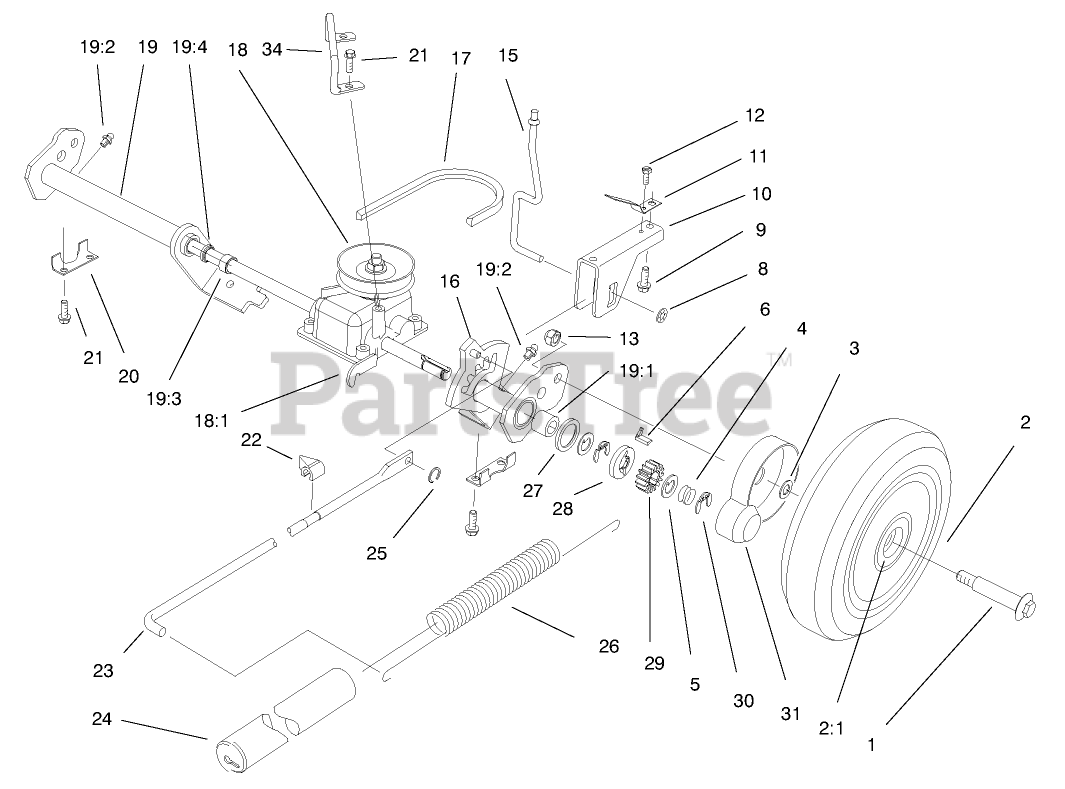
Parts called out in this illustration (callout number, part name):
1	BOLT-WHEEL
2:1	BUSHING
3	SPACER-COVER, WHEEL
4	SPRING-COMPRESSION
5	WASHER-THRUST, KEYED
6	KEY-ROCKING, LH
8	PUSHNUT
9	SCREW
10	SADDLE - HOC
12	SCREW 8 - 32 X 250
13	NUT-HEX
15	TRIGGER ROD
17	V-BELT
19	ASM - RH PIVOT ARM
19:2	FITTING-GREASE
19:3	BUSHING
19:4	SEAL-OIL
21	SCREW-HWH
22	INDICATOR-HEIGHT OF CUT
23	LINK ROD
24	COVER-SPRING
25	GRIP RING
26	SPRING-COUNTERBALANCE
27	RING-FRICTION
28	WASHER-CLUTCH
29	GEAR-PINION
30	RING-RETAINING,CLIP
31	COVER-WHEEL
